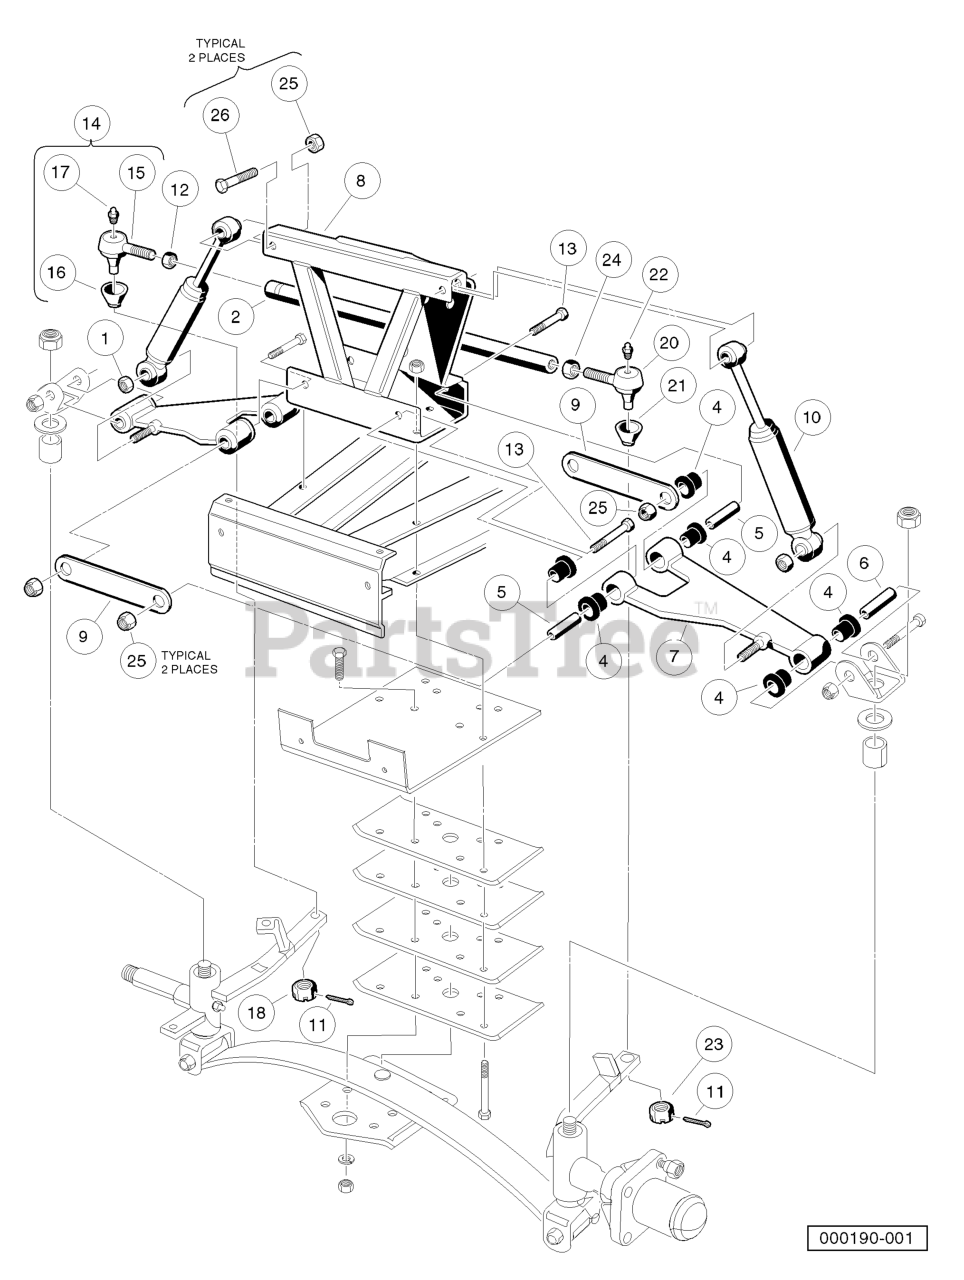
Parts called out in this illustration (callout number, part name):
1	LOCKNUT, DIMPLED
3	DELTA A PLATE SUB ASSEMBLY
4	BUSHING, URETHANE
5	SLEEVE, DELTA INNER
6	SLEEVE, DELTA OUTER
7	DeIta A-Plate
8	ASM, DELTA SHOCK & GEAR SUPPOR
9	A PLATE STRAP
10	SHOCK ABSORBER, FRONT, COMMON
11	PIN,CUT COTTER
12	NUT, 1/2-20 HEX
13	SCREW, 3/8-16 X 2.25 HX HD CAP
14	BALL JOINT, RH
15	Socket, RH Vertical
16	SEAL, VERTICAL SOCKET DUST
17	FITTING, 1/4-28 THRD FRM GREAS
18	NUT, 3/8-24 UNF HEX THICK SLOT
19	BALL JOINT, LH
20	Socket, LH Vertical
21	SEAL, VERTICAL SOCKET DUST
22	FITTING, 1/4-28 THRD FRM GREAS
23	NUT, 3/8-24 UNF HEX THICK SLOT
24	NUT, 1/2-20 HEX
25	LOCKNUT, 3/8-16 HEX
26	BOLT, 3/8-16 X 1.75 HEX
